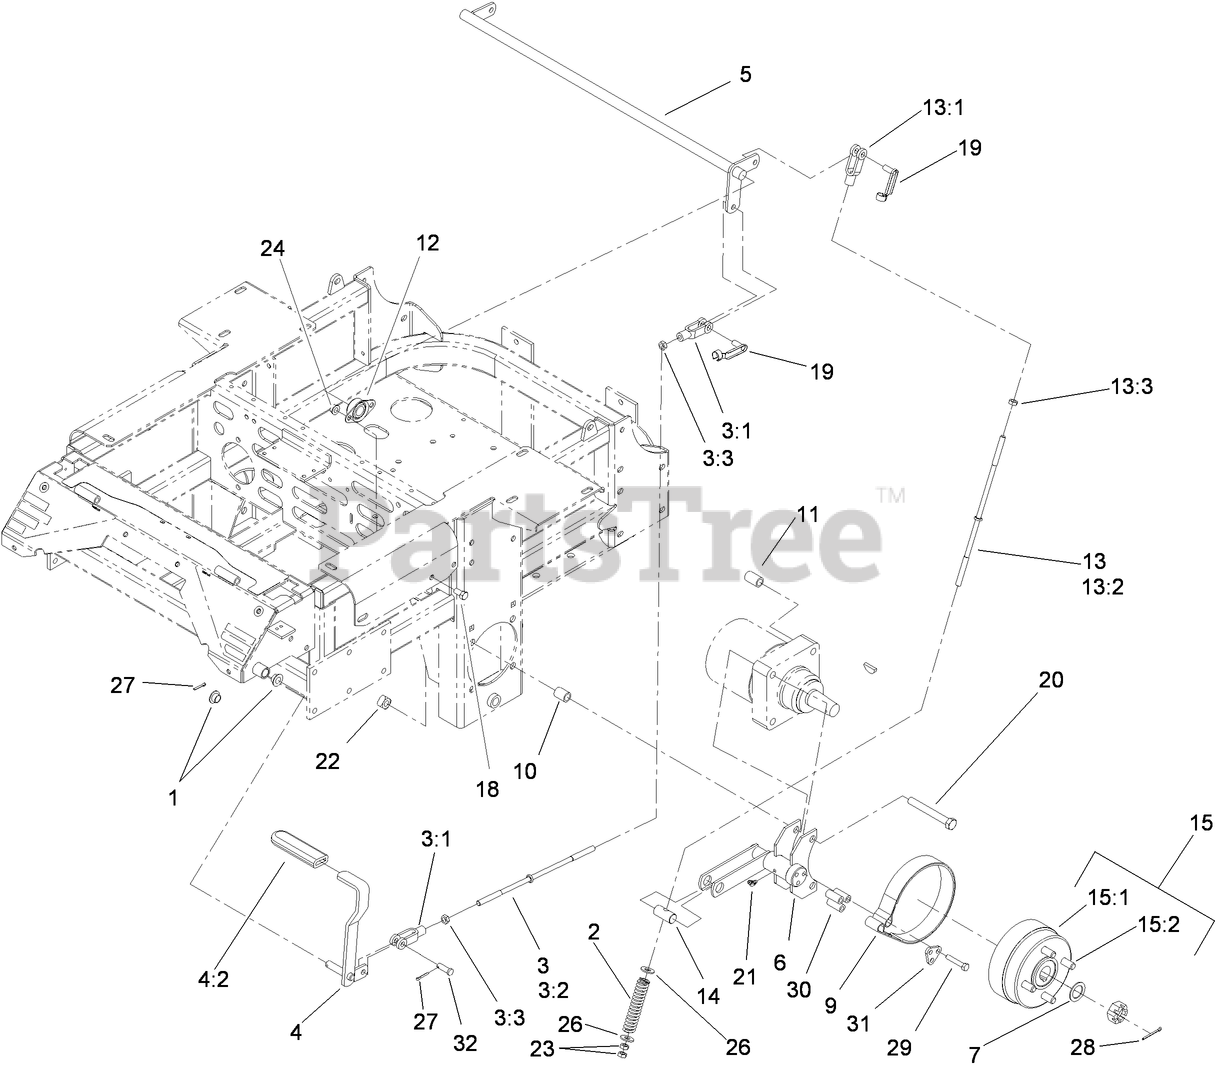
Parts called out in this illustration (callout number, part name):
1	BEARING-CONTROL
2	SPRING-BRAKE
3	Brake Rod And Yoke ASM
3:1	YOKE-LINKAGE, BRAKE
3:2	ROD-BRAKE
3:3	NUT-HEX
4	BRAKE LEVER ASM
4:2	GRIP-LEVER
5	SHAFT-BRAKE
6	BRAKE BRACKET ASM
7	WASHER-SPACER
9	BAND-BRAKE
10	SPACER-WHEEL, SHORT
11	SPACER-WHEEL, LONG
12	BEARING-FLANGE, SIDE
13	Brake Rod And Yoke ASM
13:1	YOKE-LINKAGE, BRAKE
13:2	ROD-BRAKE
13:3	NUT-HEX
14	PIN-TRUNION
15	WHEEL HUB ASM
15:1	HUB-WHEEL
15:2	STUD-WHEEL
18	SCREW-HH
19	Pin-Spring, Clevis
20	SCREW-HH
21	FITTING-GREASE
22	NUT-SQUARE, SPECIAL
23	NUT-HEX
24	NUT-HHF, WHIZ
26	WASHER-FLAT
27	PIN-COTTER
28	PIN-COTTER
29	SCREW-HH
30	SPACER
31	RETAINER-BAND, BRAKE
32	PIN-CLEVIS
